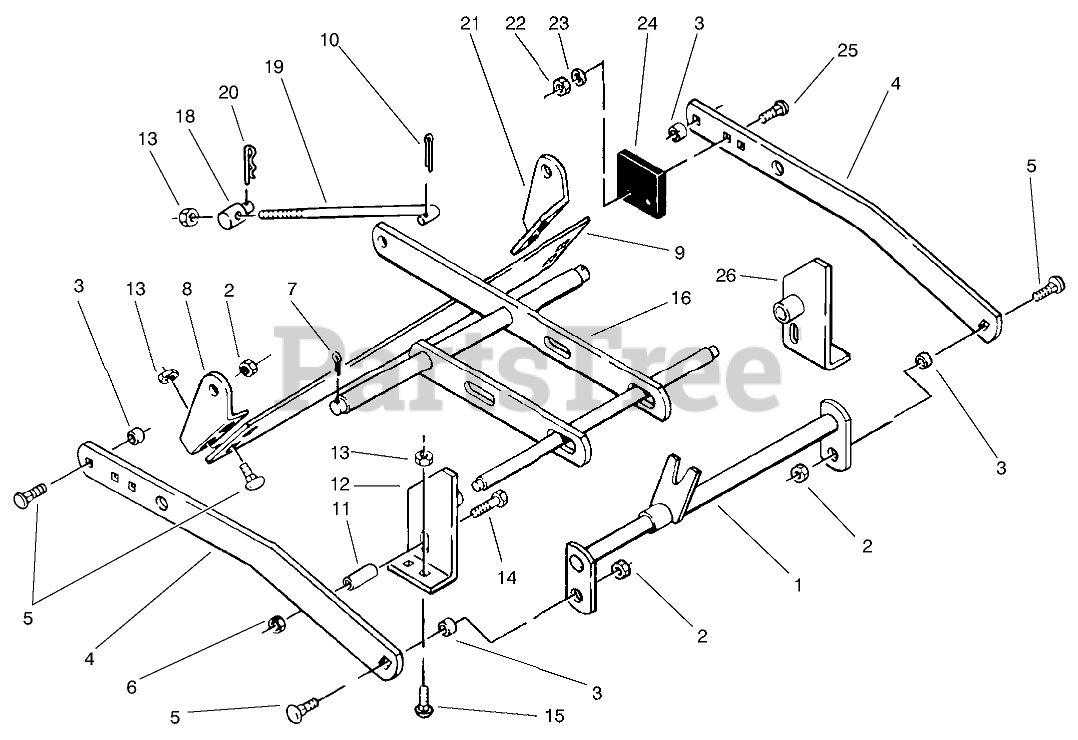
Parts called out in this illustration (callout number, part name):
1	Hitch
2	LOCKNUT-FLANGE
3	SPACER
4	Bar Draft
5	BOLT-CARR
6	NUT-LOCK, NI
7	PIN-COTTER
8	Bracket-R.H.
10	Front Shaft
11	SPACER
12	Bracket-R.H.
13	NUT-LOCK, NI
14	BOLT-CARR
15	BOLT-CARR
16	Leveler
18	TRUNNION-LIFT
19	LIFT ROD
20	PIN-HAIR
21	Bracket-L.H.
22	NUT-LOCK, NI
23	WASHER-FLAT
24	BUMPER
25	SCREW-CARR
26	Bracket-L.H.
27	PIN-COTTER
